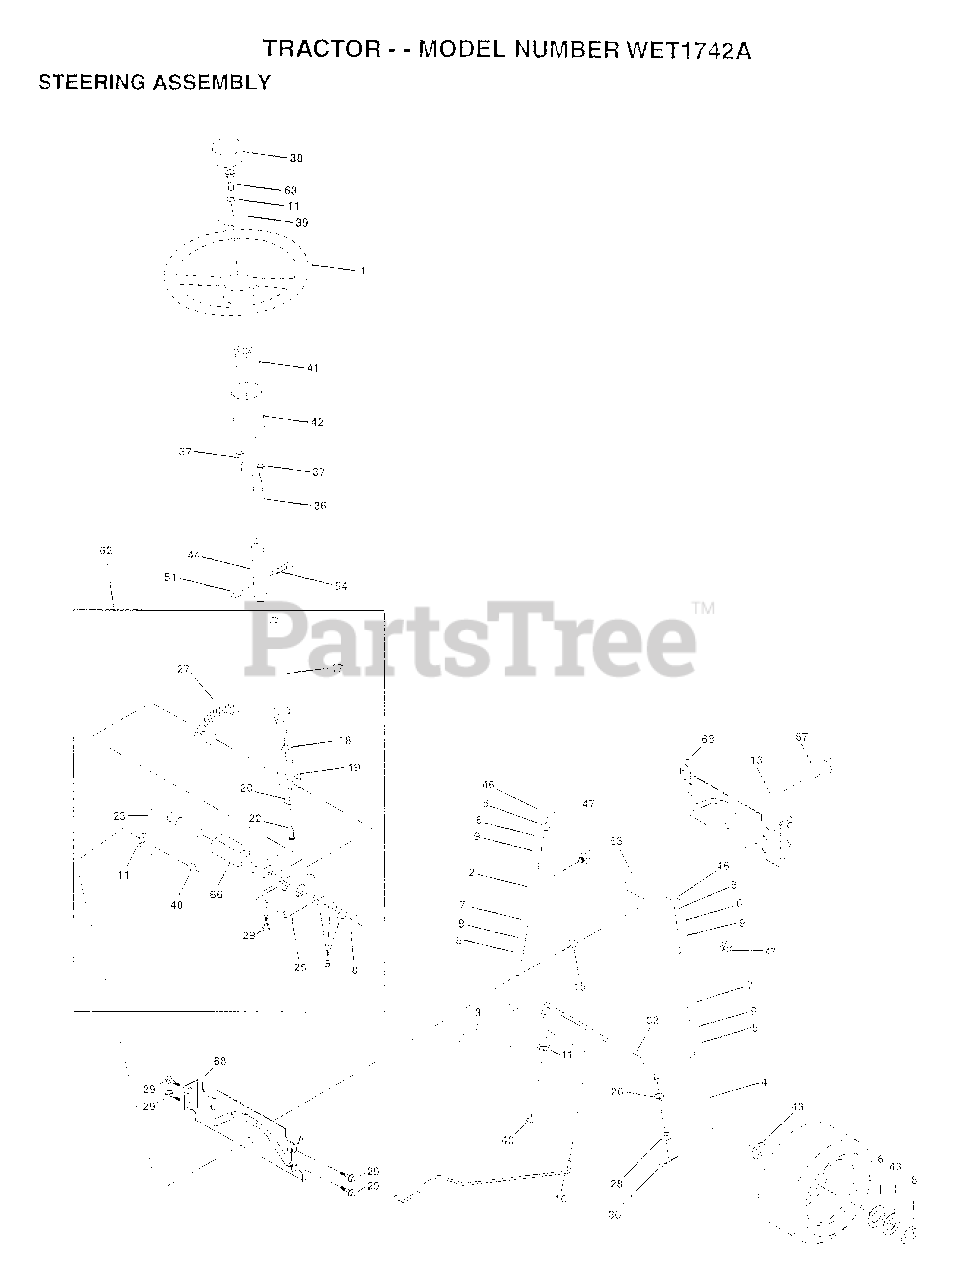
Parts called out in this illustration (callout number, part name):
1	WHEEL STR AYP BLK
2	AXLE ASM
3	SPINDLE.ASM.LH
4	"SPINDLE ASM,RH"
5	WASHER .T
6	WASHER
7	WASHER
8	RING
9	COL. SRTG. BEAR.
10	DRAGLINK-STAMPED
11	LOCKWASHER
13	BEARING AXLE
15	"NUT-LOC,FLANGE LT"
17	SHAFT ASM STEERIN
18	THRUST WASHER
19	SUPPORT.SHAFT
22	SCREW HEX SOC1/4-
25	BRKT-STEERING
26	BUSHING.DRAGLINK
27	GEAR SECTOR
28	WASHER
29	SCREW
30	COTTER PIN
32	TIE ROD
36	BUSHING.STEERING
37	"SCREW-TT,10-32 FL"
38	CAP STEER AYP
39	WASHER T
40	GRIPCO NUT
41	ADAPTER LT
42	BOOT.STEER.PL
43	WASHER
44	EXT SHAFT STEERIN
46	CAP
47	ZERK M
51	NUT
54	BOLT
62	KIT STEERING ASM
63	BOLT
65	SPACER AXLE
66	"BEARING-ARM,PITMA"
67	BOLT
68	BRACE AXLE
